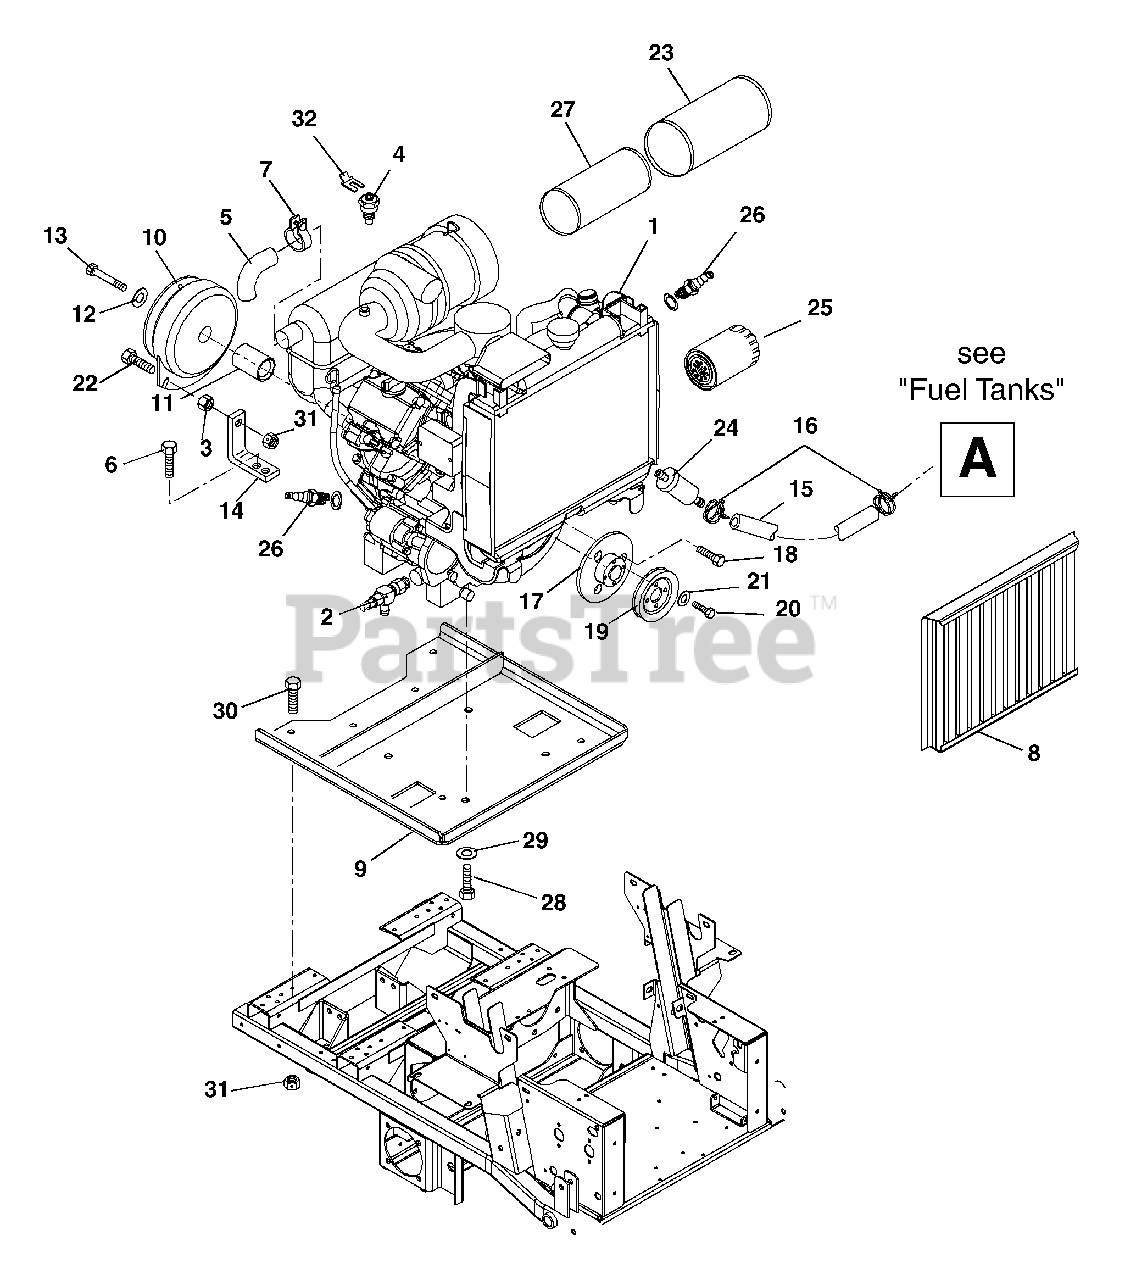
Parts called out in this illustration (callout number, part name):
1	Engine, 27HP Gas Kawasaki
2	Drain, Oil
3	Nut, Jam .312-18
4	Temperature Sender
6	Screw, Tapping .38-16 x .75 Hex Washer Head
7	Clamp, Muffler Assembly
9	Weldment, Engine Plate
10	Clutch, Electric
11	Spacer, Clutch
12	Washer, Locking .44 x .109
13	Bolt, Hex M10 x 1.5 x 60 8.8
14	Anchor, Clutch
15	Gas Line, Bulk .25 ID
16	Clamp, Hose Wire .49/.51 x .116
17	Adapter, Sheave (Kawasaki)
18	Bolt, M8-1.25 x 25
19	Sheave, Poly-V 1.0 x 3.25
20	Bolt, Hex .25-20 x .50 Grade 5
21	Washer, Locking .25 x .062 Regular
22	Bolt, Hex .31-18 x 1.50 Grade 5
23	Air Filter
24	Fuel Filter
25	Oil Filter
26	Spark Plug
27	Element, Precleaner
28	Bolt, Hex M10 x 1.5 x 25
29	Washer, Locking .44 x .109 Regular
30	Bolt, Hex .31-18 x 1.00 Grade 5
31	Nut, Locking Top Flange .38-16
32	Terminal, Male Quick Connect
